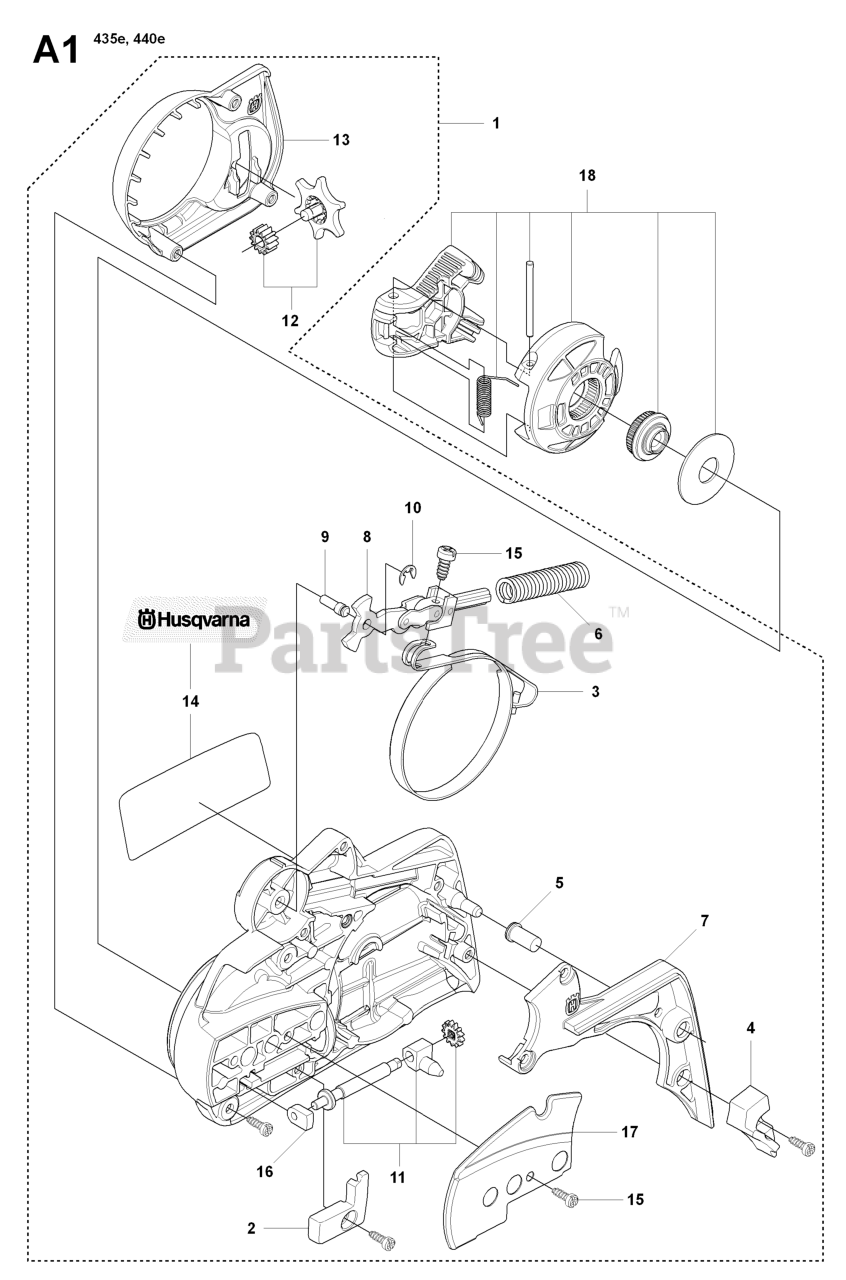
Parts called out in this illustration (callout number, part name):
1	CLUTCH COVER ASSY
3	BRAKE BAND ASSY
4	WEAR PROTECTION
6	BRAKE SPRING
11	CHAIN TENSIONER SCREW, COMP.
12	CHAIN TENSIONER WHEEL, COMP.
13	HEAT SHIELD
14	DECAL, CLUTCH HOUSING
16	RP BEARING SLEEVE
18	KNOB, COMPLETE
